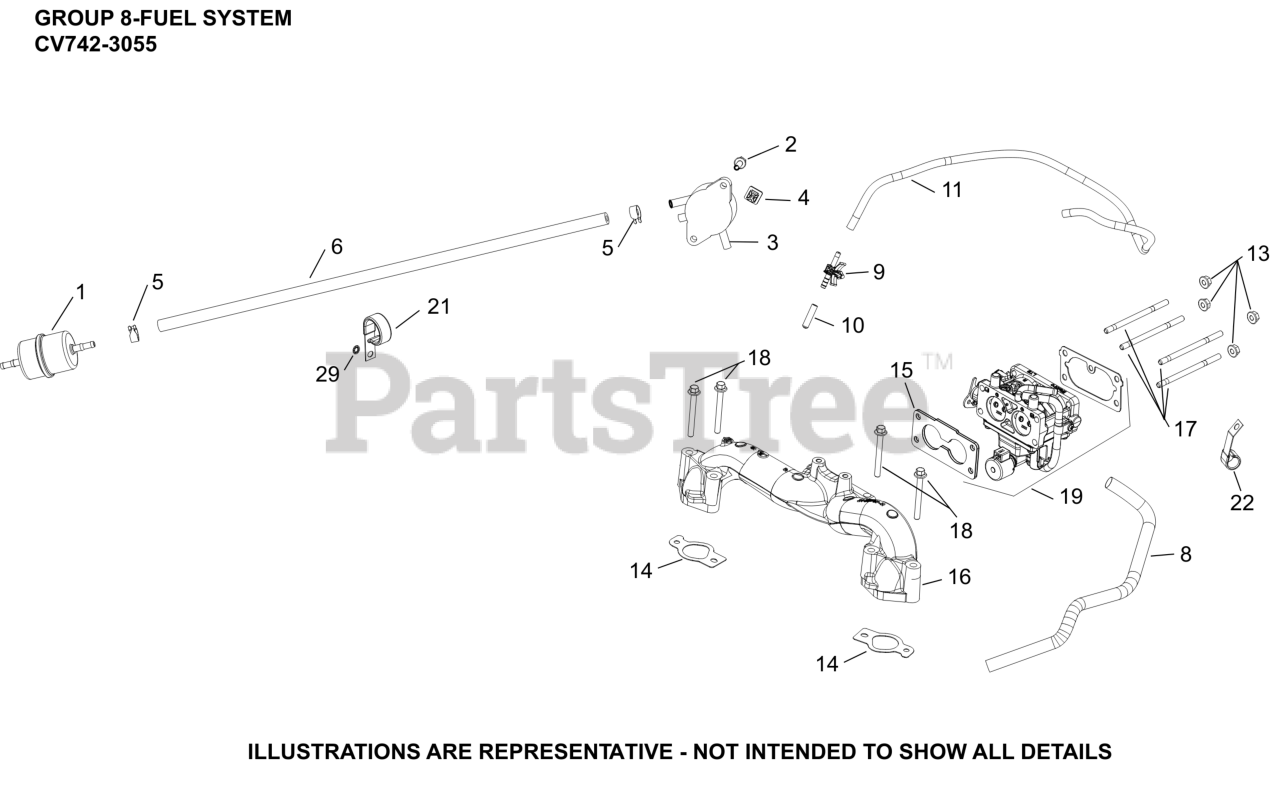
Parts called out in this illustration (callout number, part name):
1	FILTER, FUEL
2	SCREW, HEX HEAD
3	PUMP, FUEL
4	NUT, PLASTIC - BLACK
5	CLAMP, HOSE (KM)-USE 25 237 31-S
5	SPRING CLAMP, HOSE
6	HOSE,LW PERM.FUEL 24.00"-USE 25 111 81-S
6	FUEL LINE (30")-USE 25 111 81-S
6	HOSE, FUEL LOW PERMEATION 39"
8	SLEEVE, INSULATING 14"
8	SLEEVE, ANTI-ABRASION
9	CONNECTOR, EVAPORATIVE
10	CAP, MASKING
11	HOSE, EVAPORATIVE
13	NUT, HEX FLANGE-USE M-641060-S
14	KIT, INTAKE MANIFOLD GASKET
15	GASKET, CARBURETOR
16	KIT, MANIFOLD INTAKE (VERT 2BBL)-DISC.
17	STUD,M6X1.0X96
17	STUD, CARBURETOR
18	SCREW, HEX FLANGE
19	KIT, CARBURETOR COMPLETE
21	CLIP, CABLE
22	CLIP, CABLE
28	KIT, MANIFOLD INTAKE (VERTICAL 2BBL)
29	WASHER, INT TOOTH LOCK #10
NI	KIT, ACCEL PUMP REPAIR
NI	KIT, CARBURETOR REPAIR
NI	KIT, FLOAT BOWL REPLACEMENT
NI	KIT, FUEL SHUTDOWN SOLENOID
NI	KIT, SOLENOID
